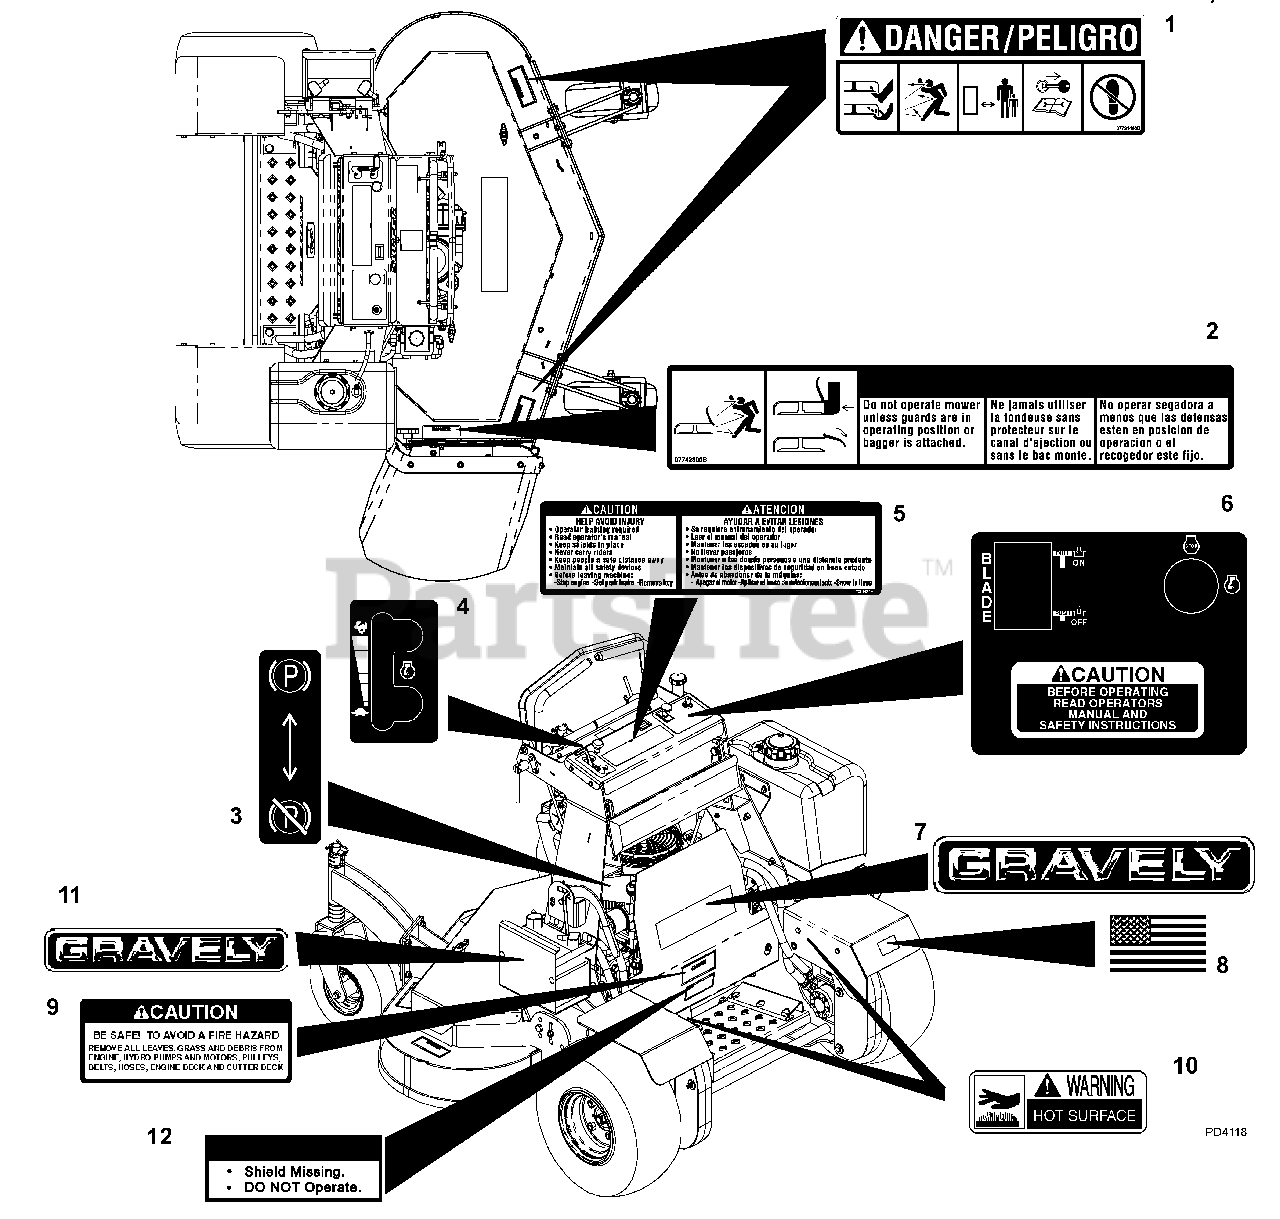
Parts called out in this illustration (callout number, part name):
1	Decal, Mower Pan Danger
2	Decal, Warning
3	Decal, Park Brake
4	Decal, Throttle
5	Decal, General Caution
6	Decal, PTO/Ignition
7	Decal, 15" Gravely Logo
8	Decal, American Flag
9	Decal, Debris
10	Decal, Warning, Hot Surface
11	Decal, Gravely Logo
12	Warning, Sheild Missing
